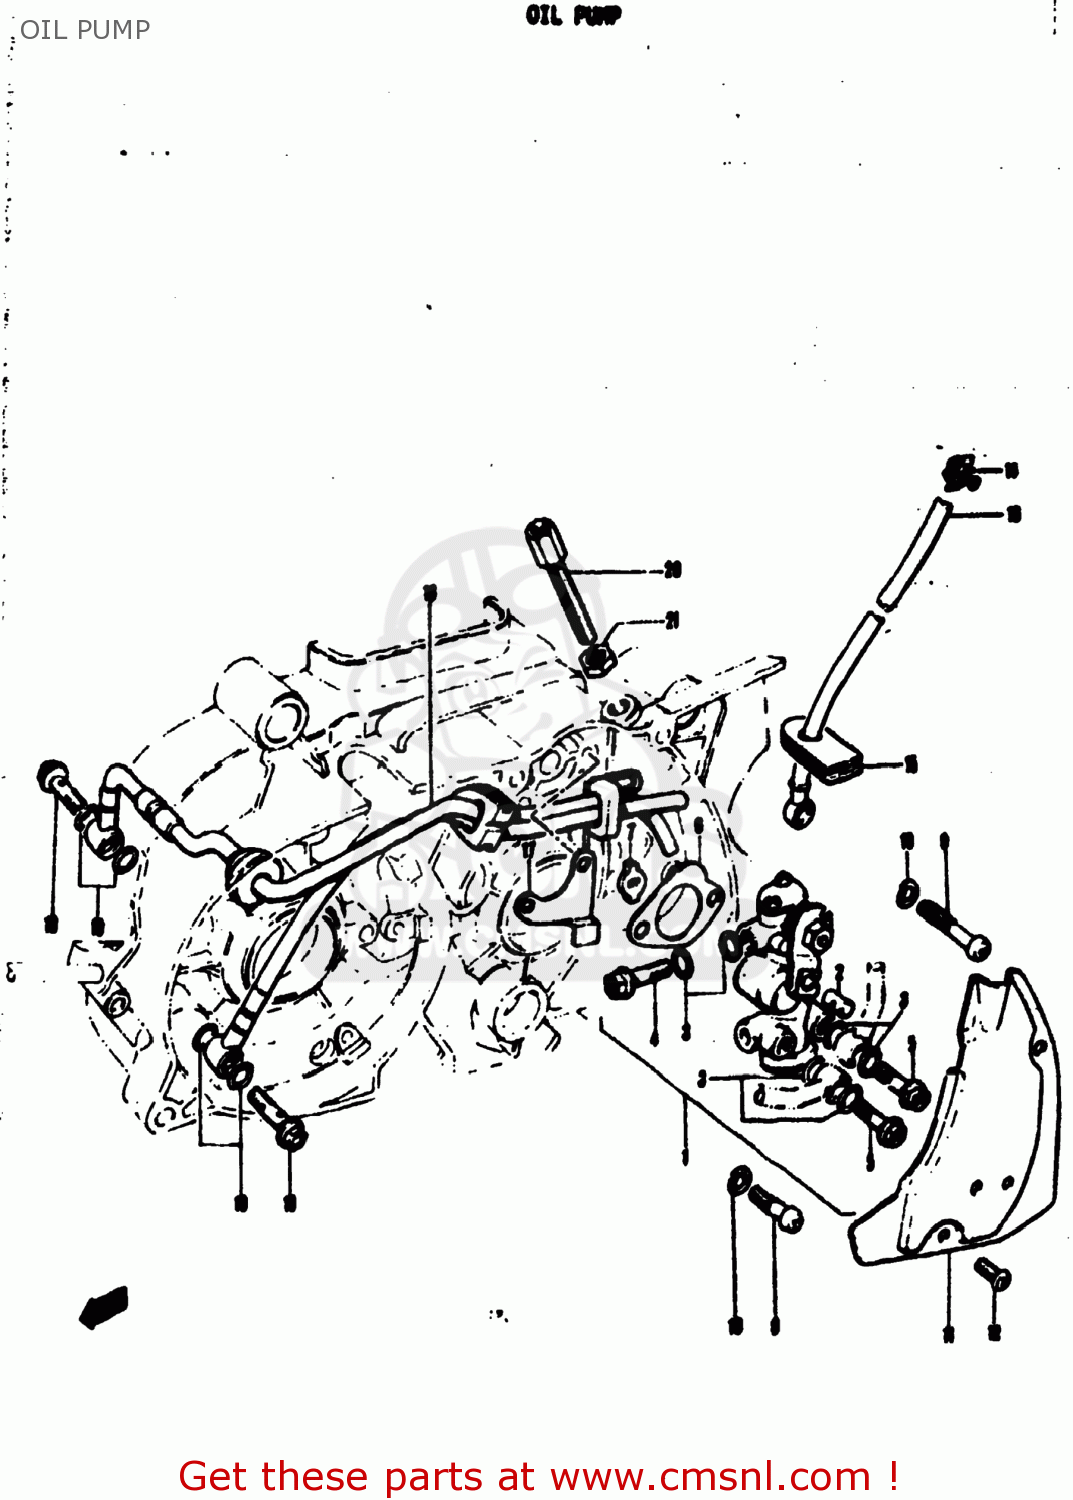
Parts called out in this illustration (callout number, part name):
1	PUMP ASSY,OIL
2	TERMINAL,CABLE
3	GASKET (NAS)
4	UNION
5	Union Bolt
6	GASKET,OIL PUMP (MCA)
7	PIECE,OIL PUMP DRIVE
8	SCREW
9	SCREW
10	LOCK WASHER
11	CAP,OIL PUMP INSPECTION
12	SCREW
13	HOSE,OIL NO.1
14	CLAMP
15	GROMMET
16	HOSE,OUTLET
17	CLAMP
18	UNION BOLT
19	GASKET (NAS)
20	BOLT
21	NUT
